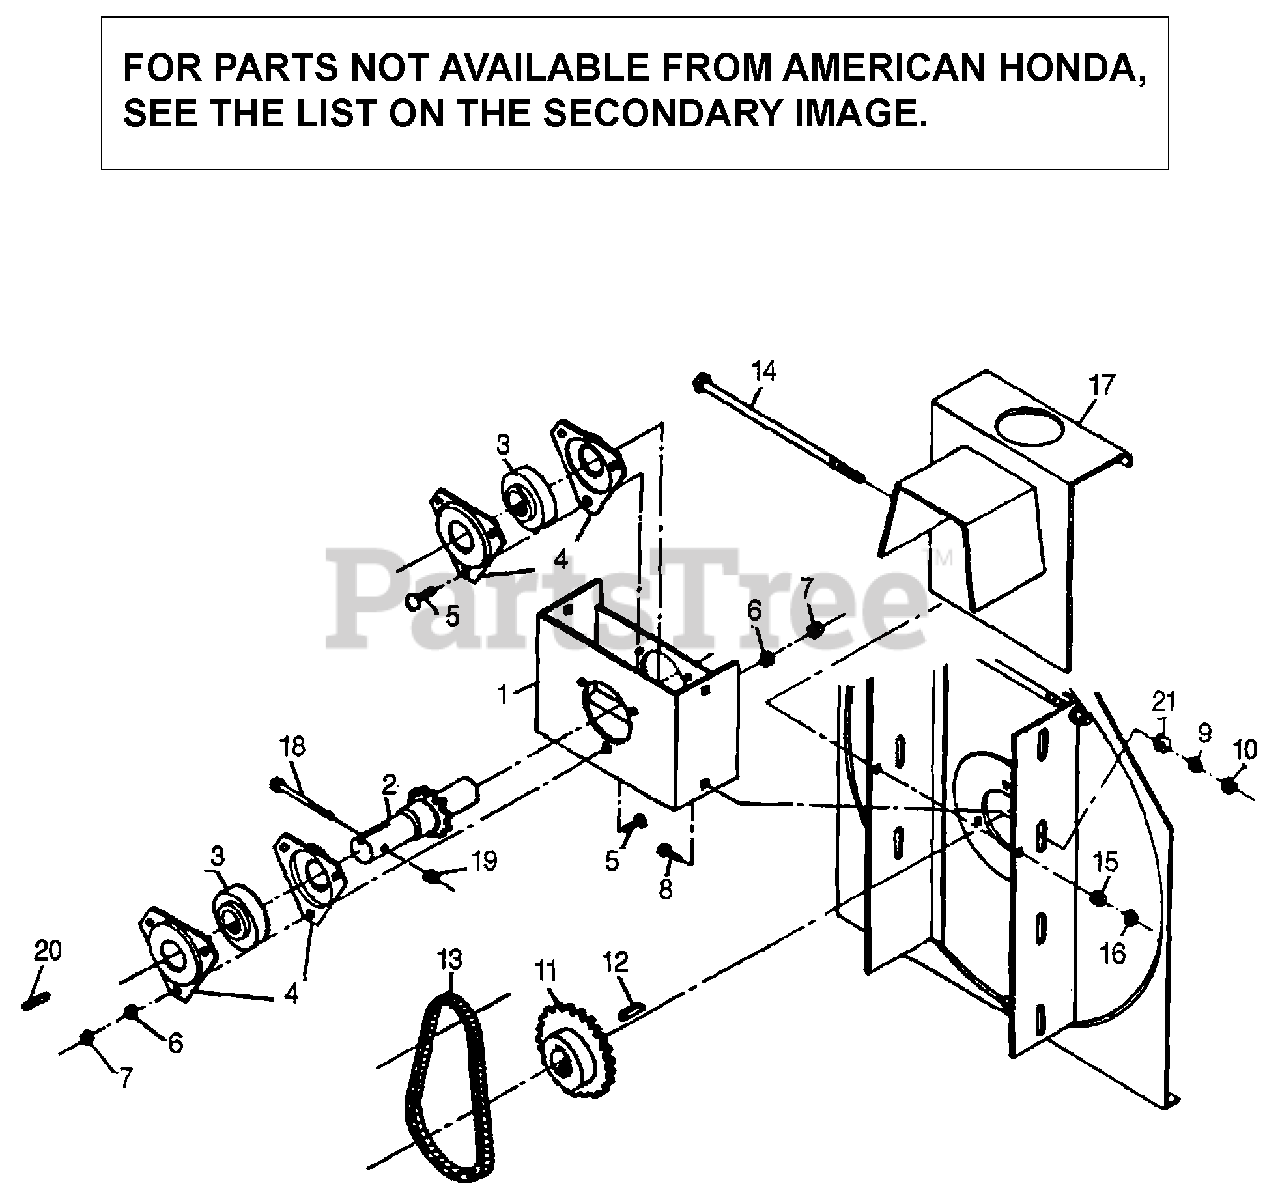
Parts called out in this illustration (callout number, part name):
1	BOX, REDUCTION
2	DRIVESHAFT, W/SPROCKET
3	BEARING, W/LOCKING SCREW
4	FLANGE, BEARING
11	SPROCKET (H40B32)
12	KEY (1/4X1/4X1") (LG.)
13	CHAIN (#40X37L)
17	PROTECTOR, P.T.O.
20	KEY (1/4X1/4X1 1/4")
